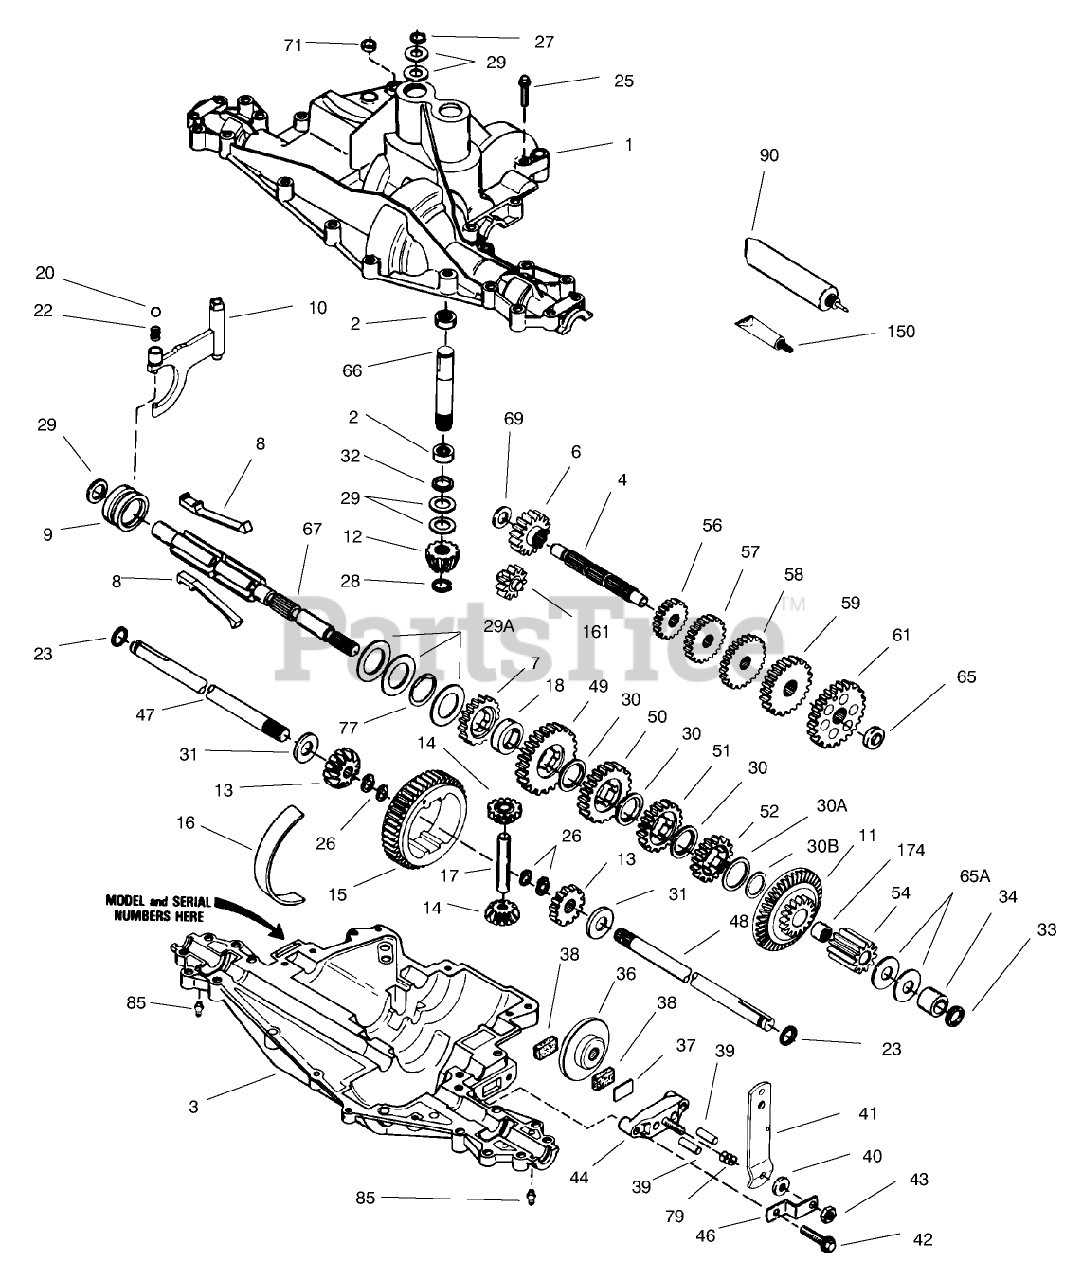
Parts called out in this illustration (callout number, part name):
1	Transaxle Cover
2	Needle Bearing
3	Transaxle Case
4	Countershaft
6	Spur Gear (16 Teeth)
7	Spur Gear (22 Teeth)
8	Shift Key
9	Shift Collar
10	Shift Rod Fork
12	Bevel Pinion (14 Teeth)
13	Bevel Gear (16 Teeth)
14	Differential Pinion
15	Ring Gear
16	Bearing Strip
17	Drive Pin
18	Neutral Spacer
20	Ball (3/8" dia.)
23	Seal Ring
27	RING-Retaining
28	RING-Retaining
29	Washer
30	Washer
30A	Washer
30B	Washer
31	Washer
36	Brake Disk
37	Brake Pad Plate
38	Brake Pad
39	Dowel Pin
40	Washer
41	Brake Lever
43	Locknut
44	Brake Pad Holder
46	Brake Lever Bracket
47	Axle (16-3/4" lg.)
49	Spur Gear (30 Teeth)
50	Spur Gear (25 Teeth)
51	Spur Gear (22 Teeth)
52	Spur Gear (19 Teeth)
54	Spur Gear (11 Teeth)
56	Spur Gear (20 Teeth)
57	Spur Gear (25 Teeth)
58	Spur Gear (28 Teeth)
59	Spur Gear (30 Teeth)
61	Spur Gear (34 Teeth)
65	Washer
65A	Washer
66	Input Shaft (3.522" lg.)
67	Shifter Brake Shaft
71	Square Cut Ring
90	Grease (32 oz. btl. Bentonite grease)
161	Reverse Idler Assembly
174	Needle Bearing
